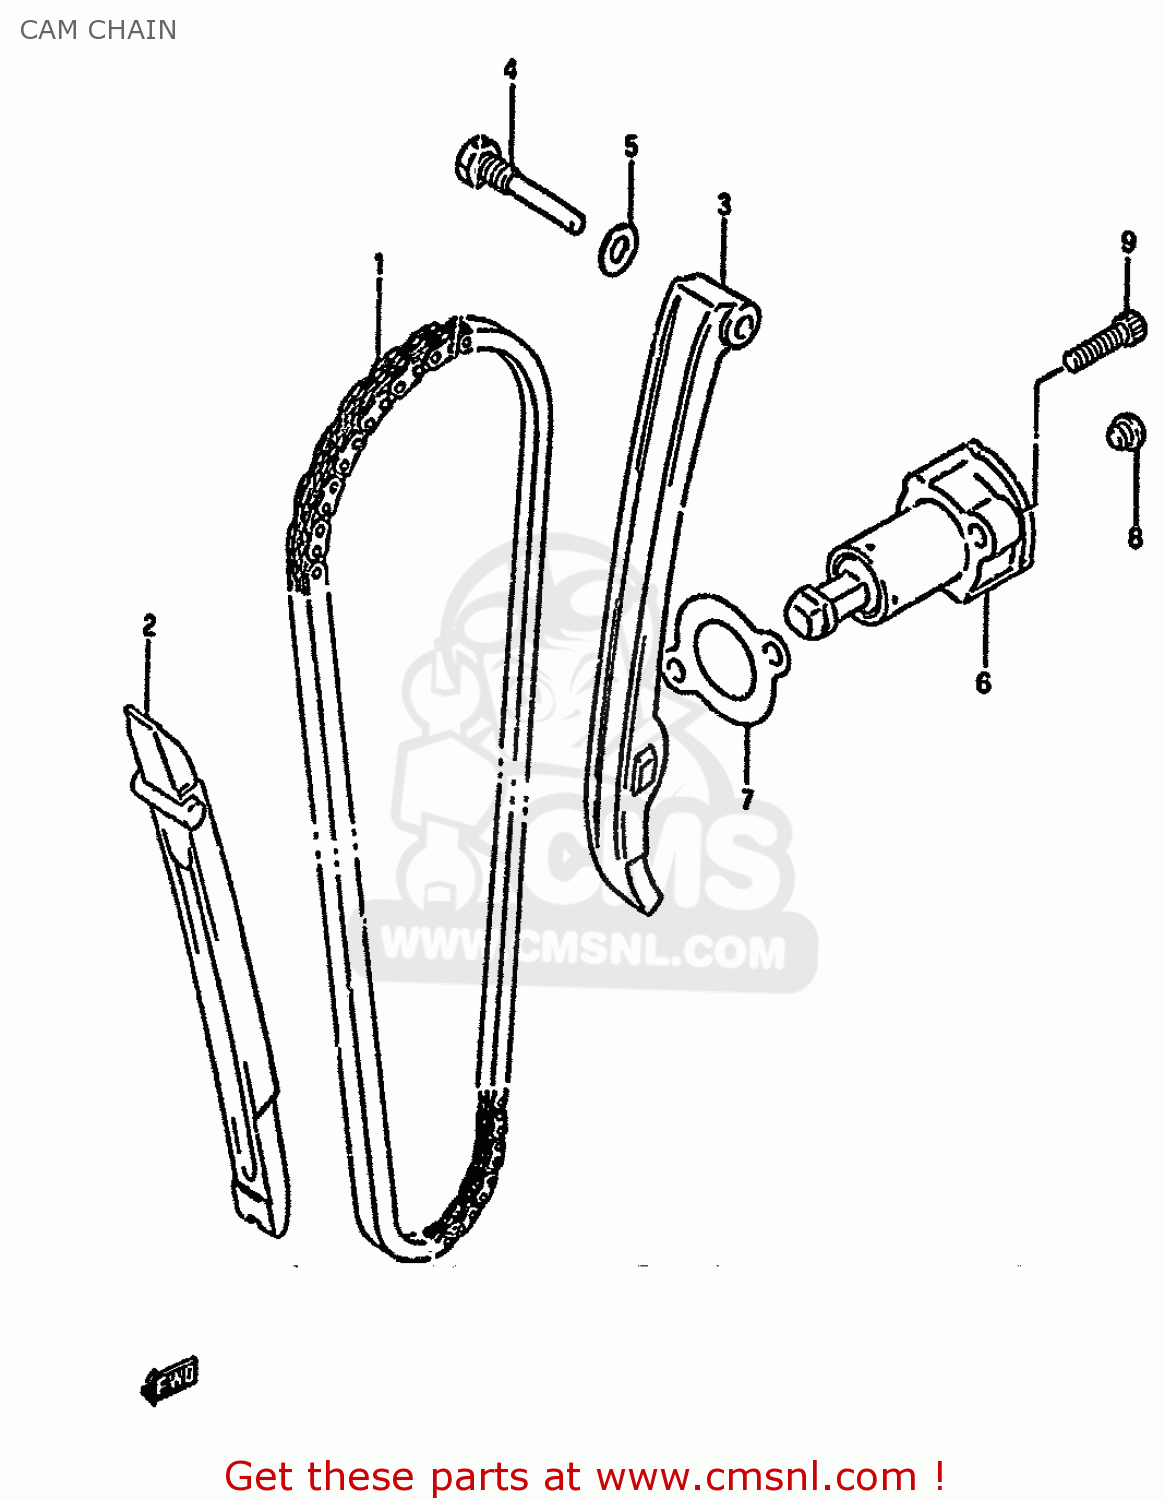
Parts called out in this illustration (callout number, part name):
1	CHAIN,CAMSHAFT DRIVE
2	GUIDE,CAM CHAIN
3	TENSIONER,CAM CHAIN
4	BOLT,CAM CHAIN TENSIONER
5	GASKET 8.2X14X1 (NAS)
6	ADJUSTER ASSY,TENSIONER
7	GASKET,TENSIONER ADJUSTER (NAS)
8	PLUG,ADJUSTER
9	BOLT
